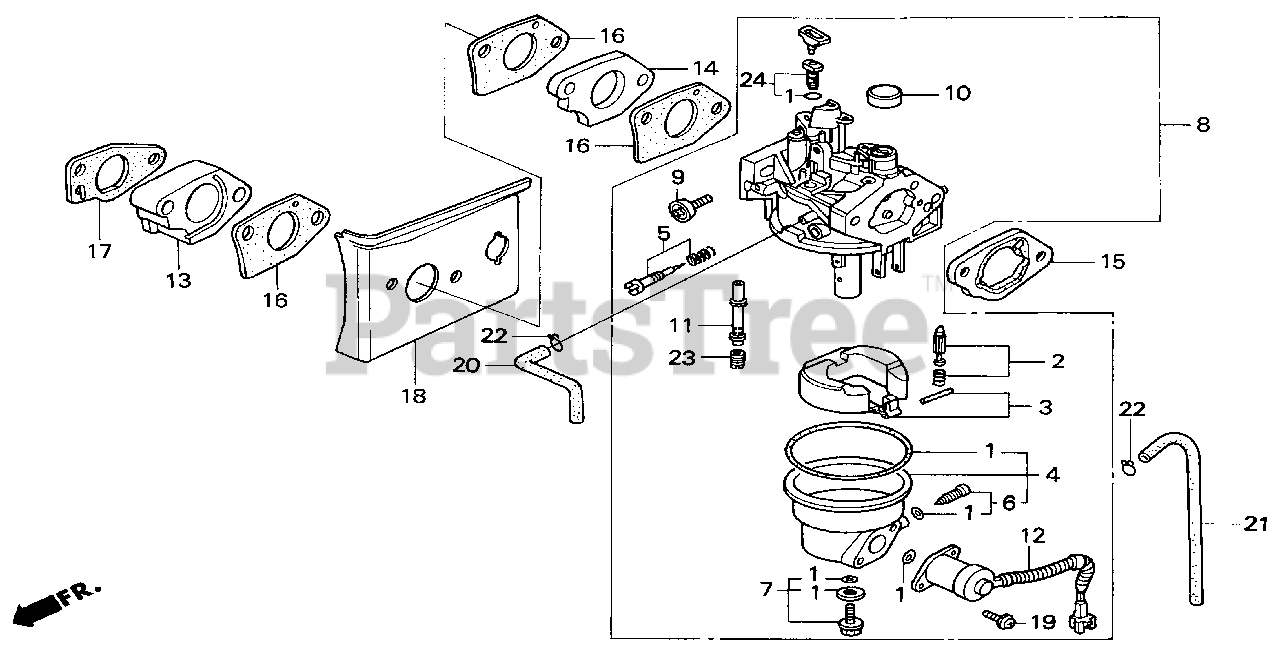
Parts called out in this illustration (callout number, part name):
1	GASKET SET (NOT AVAILABLE)
1	GASKET SET
2	VALVE SET, FLOAT
4	CHAMBER SET, FLOAT
5	SCREW SET
7	SCREW SET
8	CARBURETOR ASSY. (BE32D C)
9	SCREW, THROTTLE STOP
10	CAP, CHOKE LEVER DUST
11	NOZZLE, MAIN
12	VALVE ASSY., SOLENOID (NOT AVAILABLE)
12	VALVE ASSY., SOLENOID
13	INSULATOR, CARBURETOR
14	INSULATOR, CARBURETOR
15	SPACER, CARBURETOR
16	GASKET, CARBURETOR
17	GASKET, INSULATOR
18	GUIDE, AIR
19	SCREW-WASHER (5X12)
20	BULK HOSE, FUEL (4.5X3000) (4.5X100)
21	BULK HOSE, FUEL (4.5X3000) (4.5X250)
22	CLIP, TUBE (B8)
23	JET, MAIN (#90)
23	JET, MAIN (#92)
23	JET, MAIN (#95)
24	JET SET, PILOT (#40)
